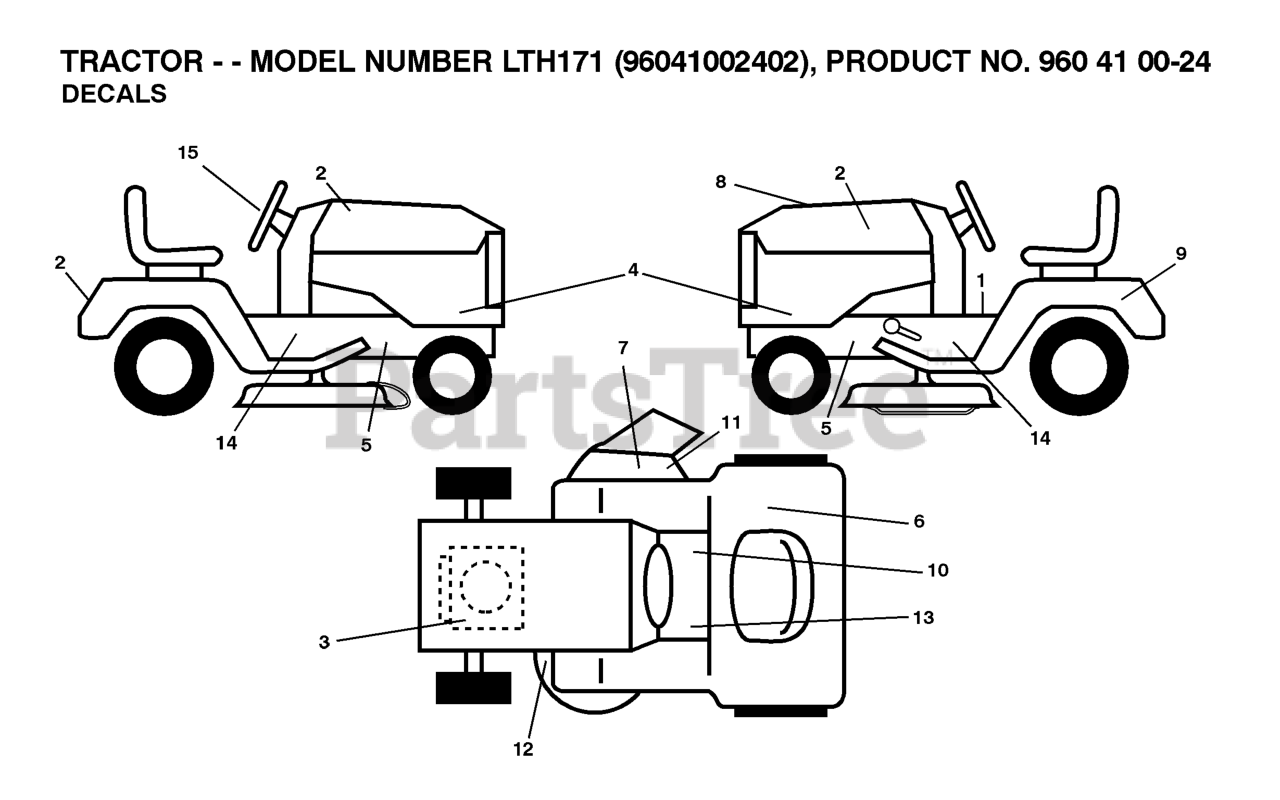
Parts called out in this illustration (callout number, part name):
1	LABEL
2	DECAL.HOOD.NAMELOGO.HUSQ
3	DECAL
6	Decal, Fender 100 DB/CE
7	DECAL.INTERNATIONL.CUTFINGER
9	DECAL BTRY SYMBOLS
10	DECAL PARK BRAKE
11	DECAL, DEFLECT WARNING
12	DECAL V BELT SCHEMATIC
13	DECAL
